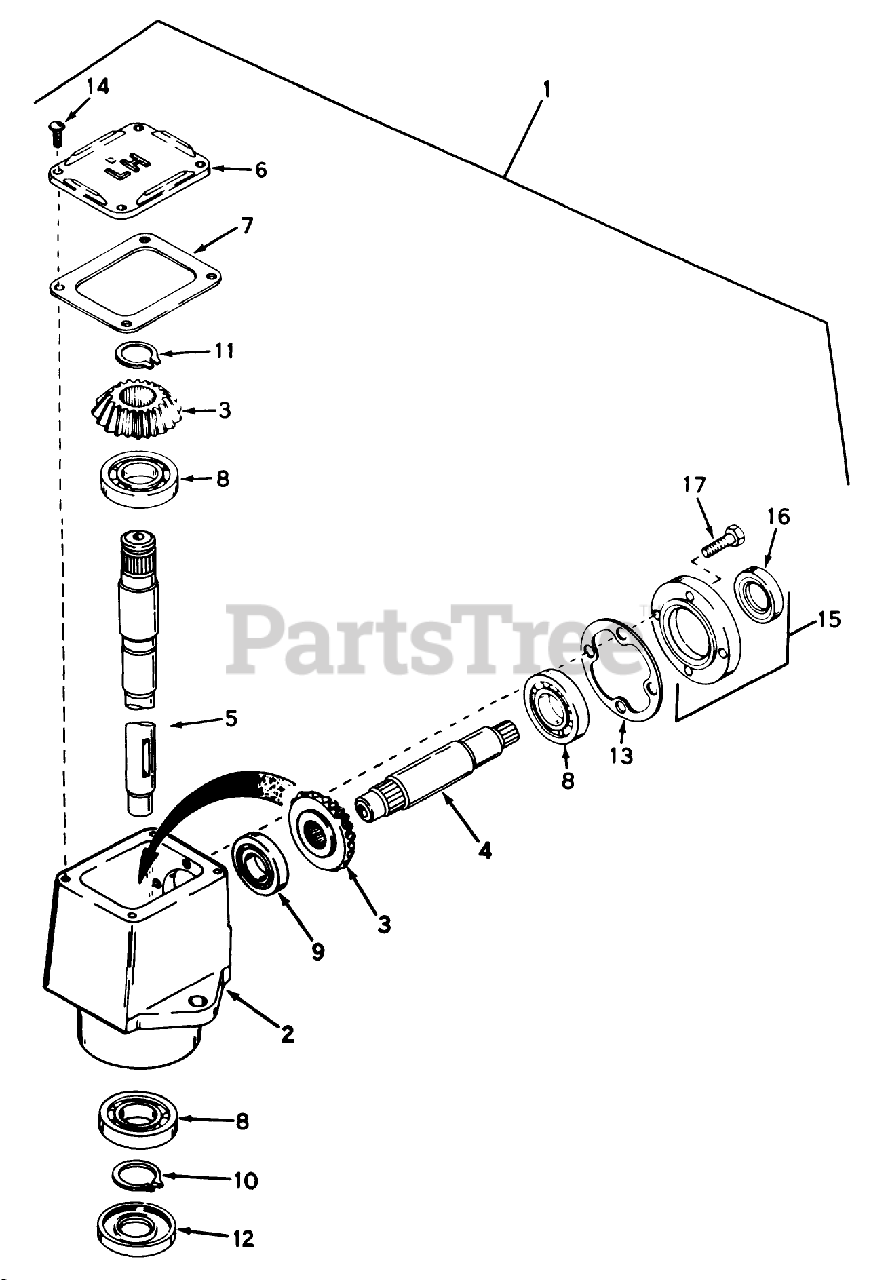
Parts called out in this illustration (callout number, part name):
1	Head Assembly-Left Hand (Incl. Ref. #2-15)
2	Housing
3	Bevel Gear
4	Shaft-Input
5	Shaft-Output
6	Cover
7	Gasket
8	Bearing
9	Bearing
10	Ring-Snap
11	Ring-Snap
13	Gasket
14	Screw
15	Cap & Seal Assy.-Retainer (Incl. Ref. #16 & 17)
16	Oil Seal
17	Ring Set (STD)
